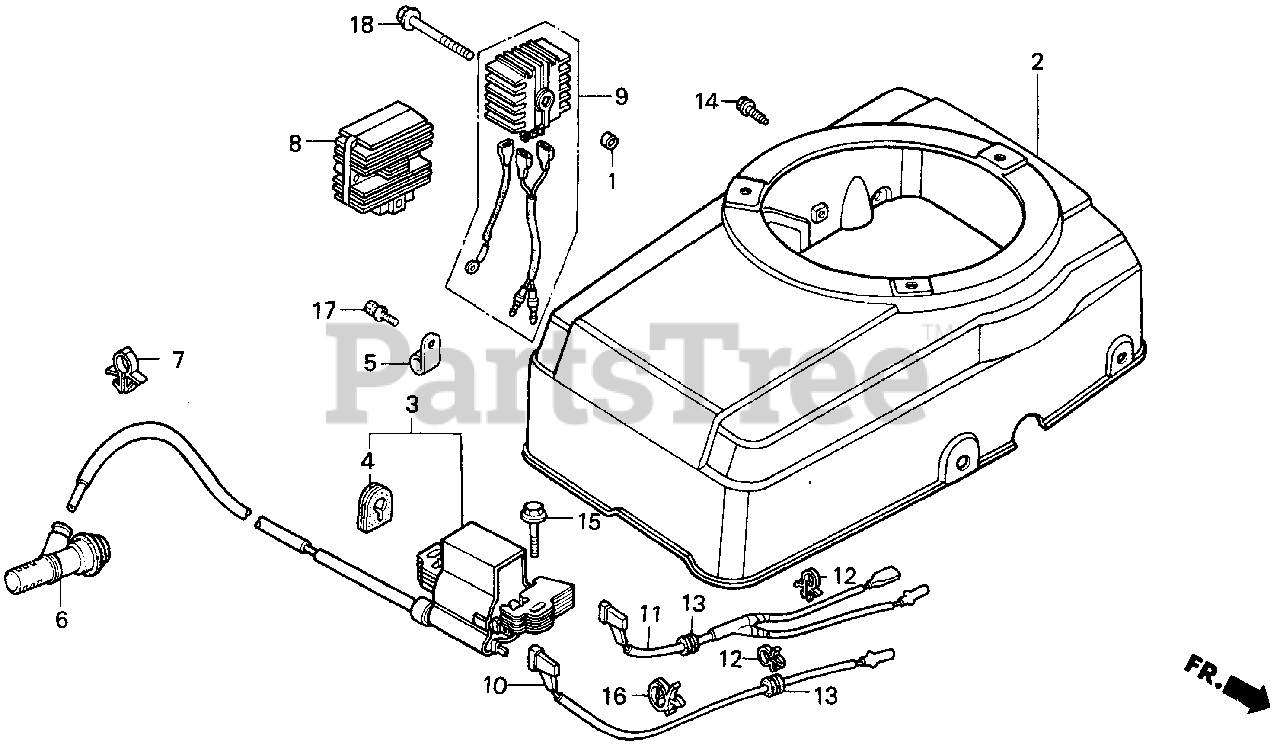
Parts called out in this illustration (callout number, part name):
2	COVER, FAN *R8* (BRIGHT RED)
3	COIL ASSY., IGNITION
4	GROMMET, IGNITION
5	CLAMP, IGNITION WIRE
6	CAP ASSY., NOISE SUPPRESSOR
8	RECTIFIER ASSY., REGULATOR
11	WIRE, STOP SWITCH
12	HOLDER, STOP SWITCH WIRE
13	GROMMET, WIRE
14	BOLT, FLANGE (6X12) (CT200)
15	BOLT, FLANGE (6X28)
17	SCREW-WASHER (5X12)
